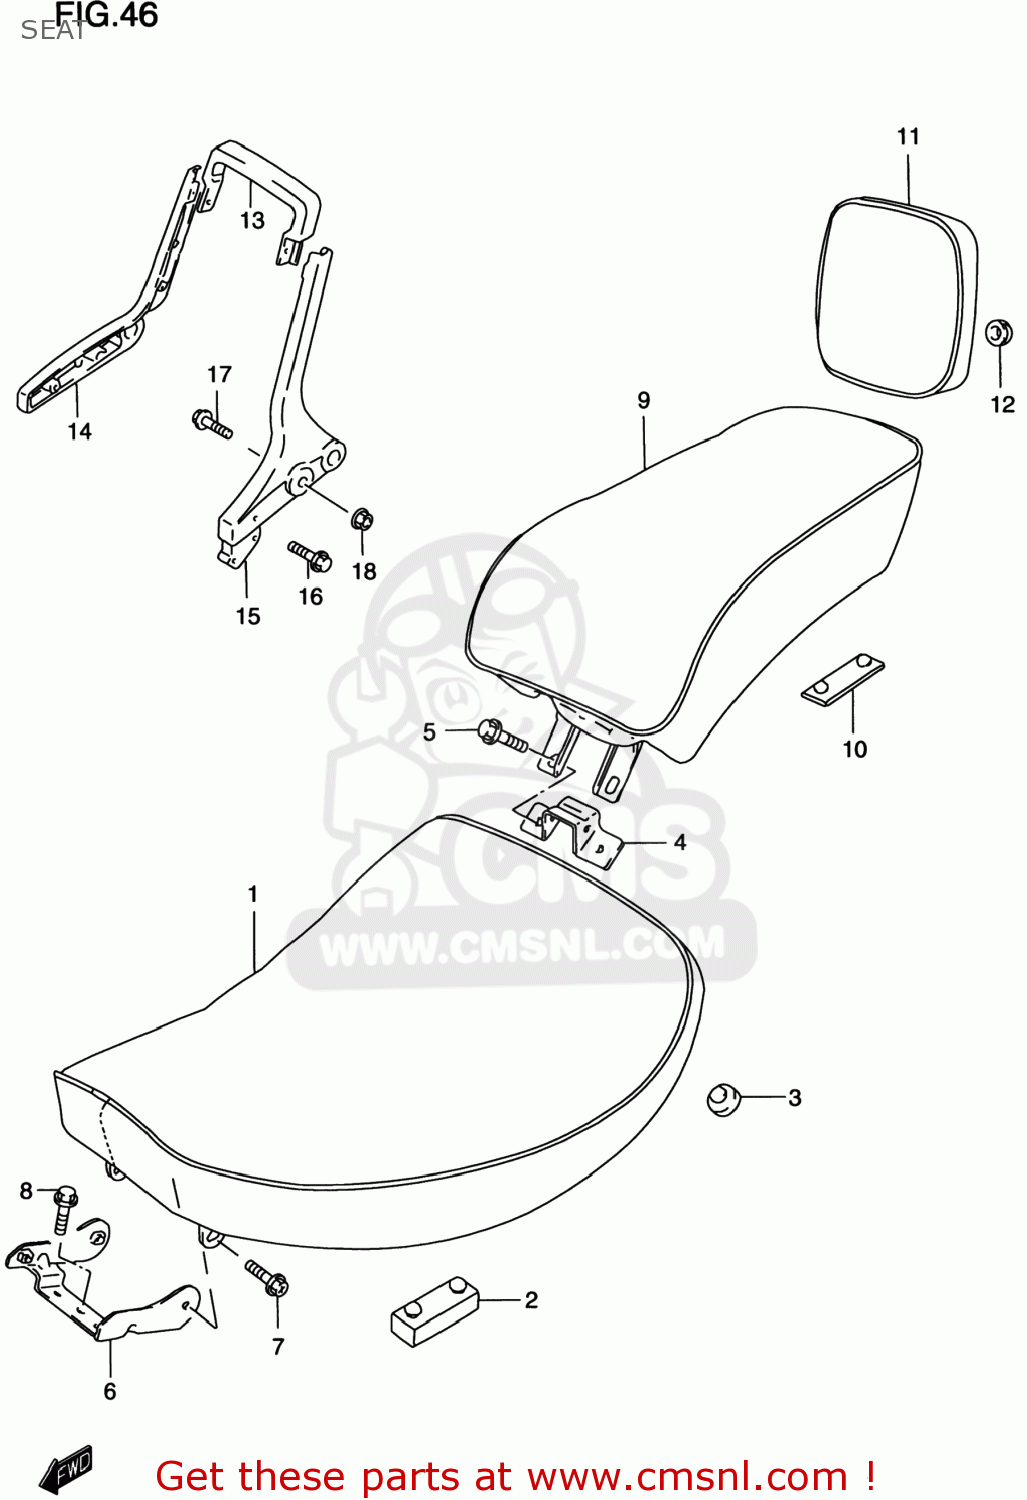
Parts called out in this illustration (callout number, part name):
1	SEAT ASSY
2	CUSHION,SEAT
3	CUSHION
4	PLATE,FR SEAT HOOK & RR
5	BOLT(6X16)
6	BRACKET,SEAT FR
7	BOLT(6X16)
8	BOLT
9	SEAT ASSY,PILLION
10	CUSHION
11	PAD ASSY,SEAT
12	CUSHION
13	HANDLE,PILLION RIDER UPR
14	HANDLE,PILLION RIDER,R
15	HANDLE,PILLION RIDER
16	BOLT
17	BOLT
18	NUT
